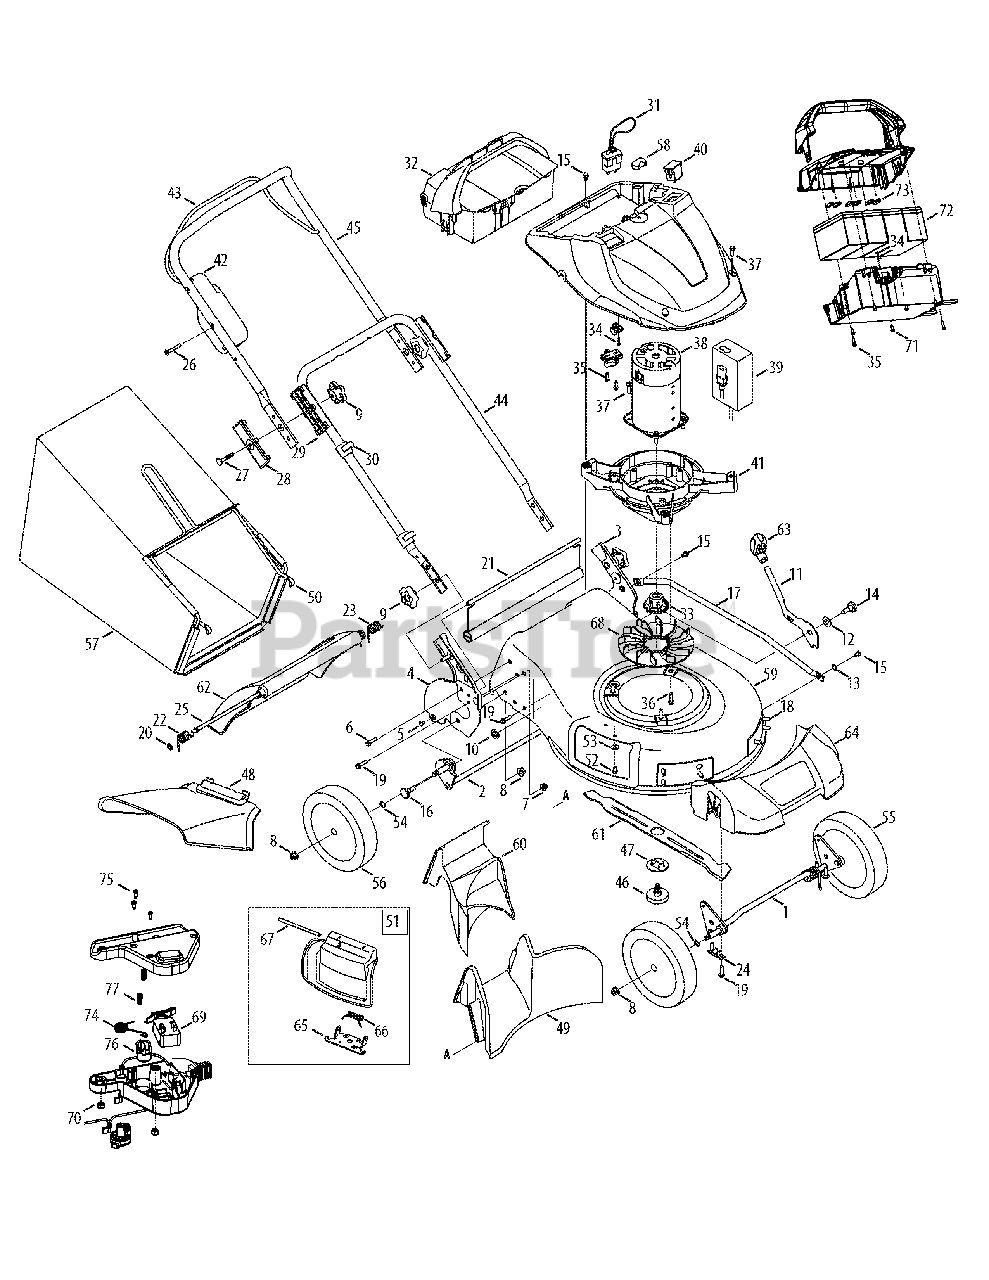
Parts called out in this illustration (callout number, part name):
1	Front Bracket Assembly
2	Rear Bracket Assembly
3	LH Bracket Assembly
4	RH Bracket Assembly
5	Screw, #10-16 x .500
6	Hex Screw, 5/16-18:.625
7	Flangelock Nut, 5/16-18
8	Flangelock Nut, 3/16-18
10	Spacer, .515 X 1.00 X .310 LG
11	Height Lever
12	Bell Washer, .510 x 1.14 x .040
13	Wave Washer, .385 ID X .598 OD
14	Shoulder Screw, .50 x .66
15	Shoulder Screw, 1/4-20:0.50
16	Shoulder Screw, .500 x .434
17	Height Bracket
18	Hi-lo Screw, :5/16-14:.750
19	Hi-lo Screw, 1/4-15:1.00
20	Speed Nut
21	Trailshield
22	RH Torsion Spring
23	LH Torsion Spring
26	Flat Screw, 1/4-20:1.75
27	Carrriage Bolt, 5/16-18:2.50
28	Upper Handle Insulator
29	Lower Handle Insulator
30	Cable Guide
32	Replaceable Battery
33	Fan Assembly
34	Screw, 1.59 x .610
35	Hi-lo Screw, #12-16:.75
36	Screw, 5/16-12:0.750
37	Hi-lo Screw, 1/4-15:0.750
39	Battery Charger
40	Battery Level Indicator
41	Motor Bracket
42	Switch Assembly
43	Switch Bail
45	Upper Handle
46	Blade Assembly Bolt
47	Blade Locking Plate
48	Discharge Chute
49	Rear Baffle
50	Grass Bag Frame
51	Mulch Plug
52	Taptite Screw, 1/4-20 x .500
53	Bell Washer, .265 x .75 x .062
54	Wave Washer, .510 x .750 x .017
55	Rear Wheel
56	Front Wheel
58	Locking Knob
60	Mulch Plug
63	Height Adjust Knob
64	Front Axle Cover
65	Chute Deflector Adaptor
66	Torsion Spring, .290 ID x 1.68
67	Hinge Pin, .250
69	Switch Button
70	Hexlock Nut, 1/4-20
71	Screw, #12-16:.50
72	12V Battery
73	Battery Jumper
74	Torsion Spring
75	Screw, 10-9 x .50
76	Bail Lock
77	Compression Spring, .260 x .687
